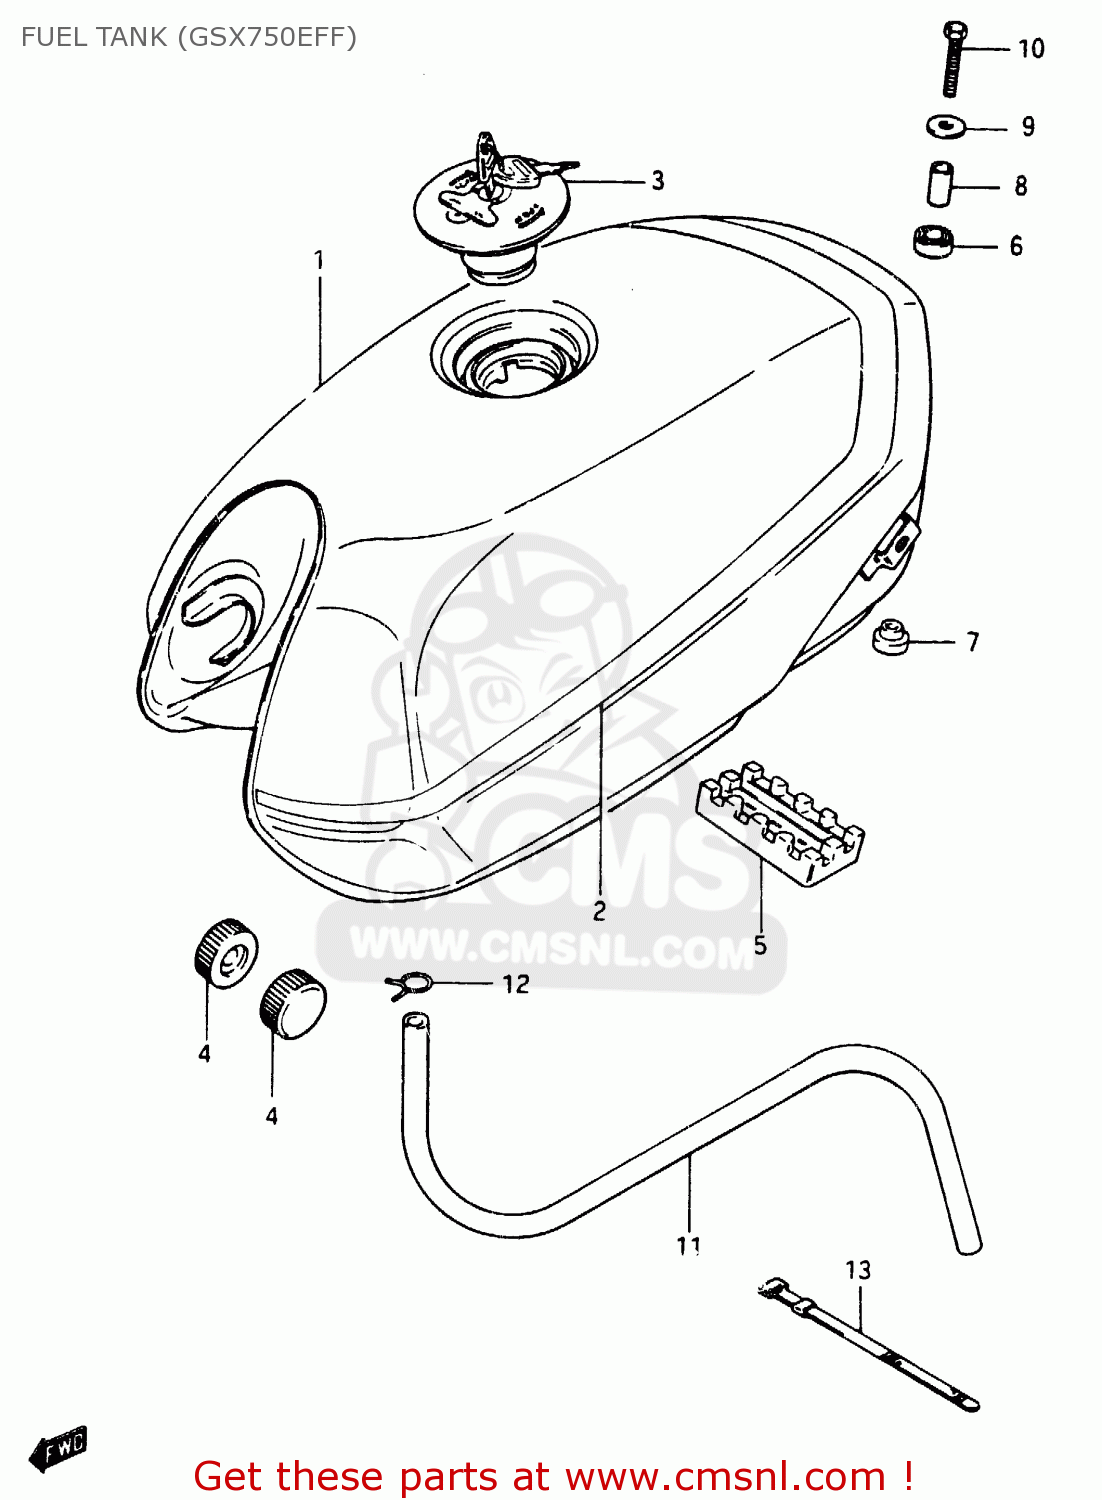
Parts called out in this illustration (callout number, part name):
1	TANK, FUEL
2	TAPE SET, FUEL TANK (RED)
3	CAP, FILLER
4	CUSHION
5	CUSHION,FUEL TANK CTR
6	CUSHION
7	CUSHION
8	SPACER
9	WASHER (6.5X24X1.6)
10	BOLT
11	HOSE,FUEL
12	CLIP
13	CLIP(ID:16)
